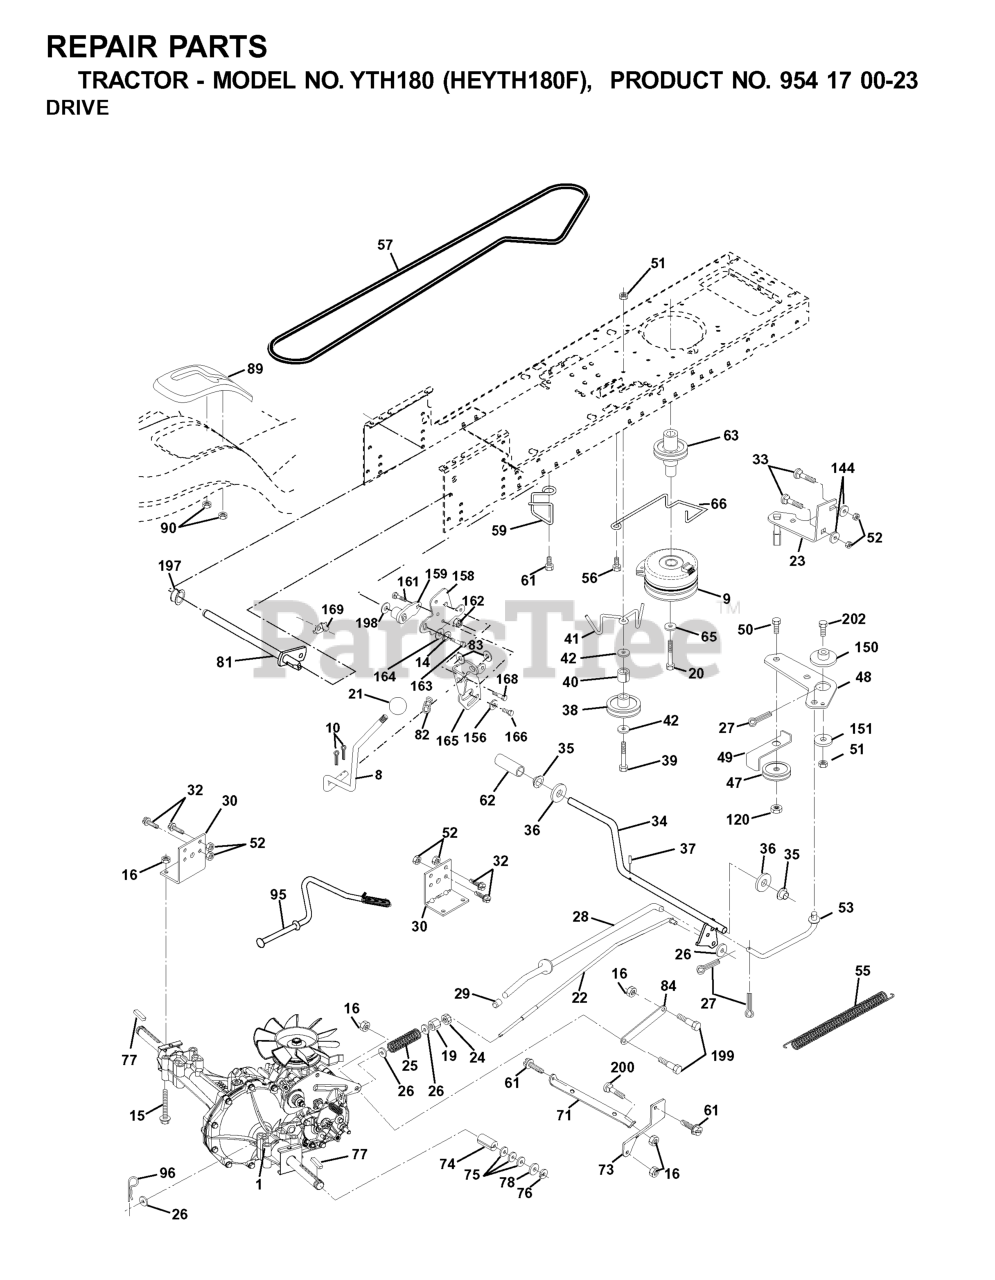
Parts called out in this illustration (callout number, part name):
8	ROD SHIFT FENDER ADJUST STLT
9	ELECTRIC CLUTCH
10	PIN COTTER
14	LOCKWASHER
15	BOLT HEX 5/16-18 GR 5
16	NUT.71038.31-18.HEX.NYLOCK
19	NUT
20	BOLT HEX
21	KNOB.DUCKHEAD.1/2
22	ROD BRAKE HYDRO
24	NUT
25	SPRING ROD LT
26	WASHER
27	COTTER PIN
28	ROD, PARKING BRAKE
29	PLUNGER CAP
30	BRKT, TRNSXLE MNT 20"
32	BOLT
33	RP BOLT 5/16-18 X3/4 ZN/YEL GR
34	SHAFT, FOOT PEDAL
35	BEARING.NYLON
37	DRIVE PIN
38	PULLEY.FLAT
39	BOLT
40	SPACER, SPLIT
41	KEEPER, BELT IDLER
42	WASHER
47	IDLER PULLEY
48	BELLCRANK, CLUTCH
49	RETAIN BELT
50	BOLT
52	LOCKNUT
53	LINK, CLUTCH LT
55	SPRING, RETURN LT
56	SCREW THDROL 3/8-16 X 1-1/2
57	DRIVE BELT, LTH & YTH TRACTORS
59	KEEPER, BELT CENTER
61	SCREW 3/8-16X3/4
62	COVER, PEDAL (1 2)
63	PULLEY, ENGINE
65	LOCKWASHER
66	KEEPER BELT ENGINE
71	STRAP TORQUE LH HYDRO
73	STRAP TORQUE RH HYDRO
74	SPACER AXLE
77	SQUARE KEY
81	SHAFT ASM CROSS TAPERED
82	SHIFT SPRING
83	WASHER
84	LINK TRANSAXLE
89	SHIFT CONSOLE
90	NUT.PUSH.3/16
95	CONTROL ASM. BYPASS HYDRO
96	RETAINER M
120	NUT LOCK FLG 3/8-16 UNC
144	Washer 11/32 x 5/8 x 16 Ga SD
150	SPACER, RETAINER
151	WASHER 12/32X2X10GA
156	WASHER.SRRTD.5/16
158	BRACKET
159	HUB
161	BOLT
162	NUT.CROWNLOCK.1/4
164	Washer 5/8 x .281 x 10 Ga.
165	RP BRACKET
168	BOLT.SHOULDER.5/16-18X
169	PLATE.FASTENING.CROSS.SHAFT
197	NYLINER SNAP 5/8" ID
198	WASHER.NYL.7/8IDX.105"HYD CR
199	BOLT SHOULDER 5/16-18 UNC
202	BOLT.3/8-16X1.50
